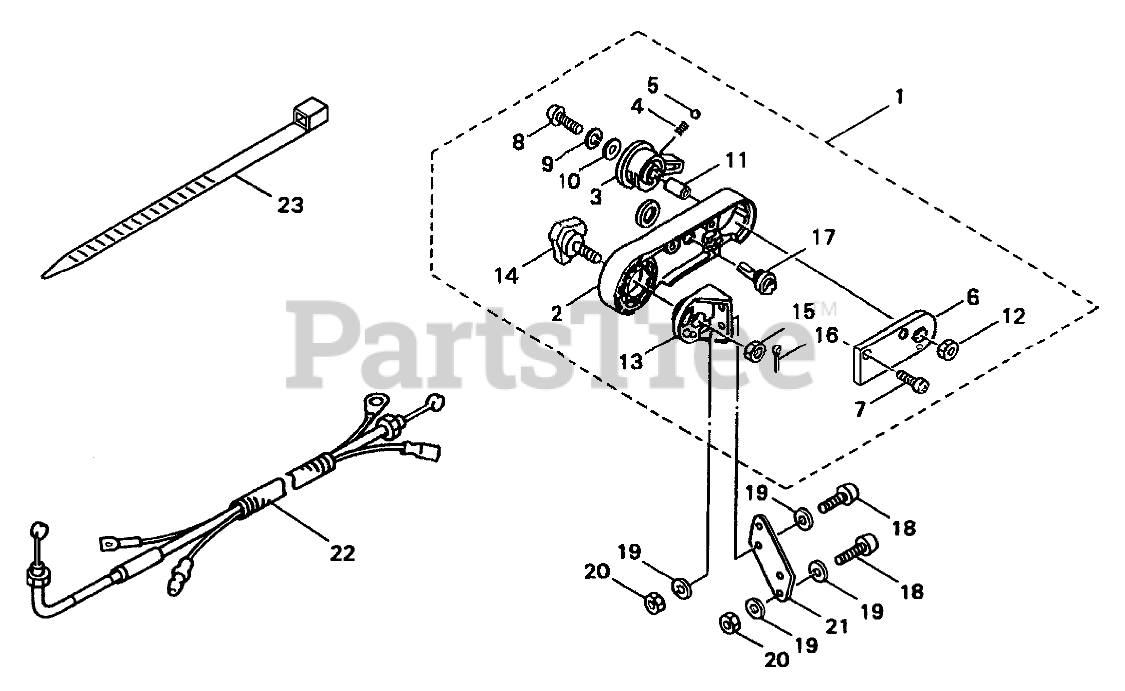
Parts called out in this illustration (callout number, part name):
1	Throttle Lever Assembly
3	LEVER
4	SPRING
7	TAPPING SCREW
8	SCREW
9	SPRING WASHER
10	WASHER
11	COLLAR
13	Flange
14	Bolt-Knob
15	NYLON NUT
16	COLTER PIN
17	SWITCH
18	SCREW
19	WASHER
21	Plate
22	THROTTLE CABLE ASSY
